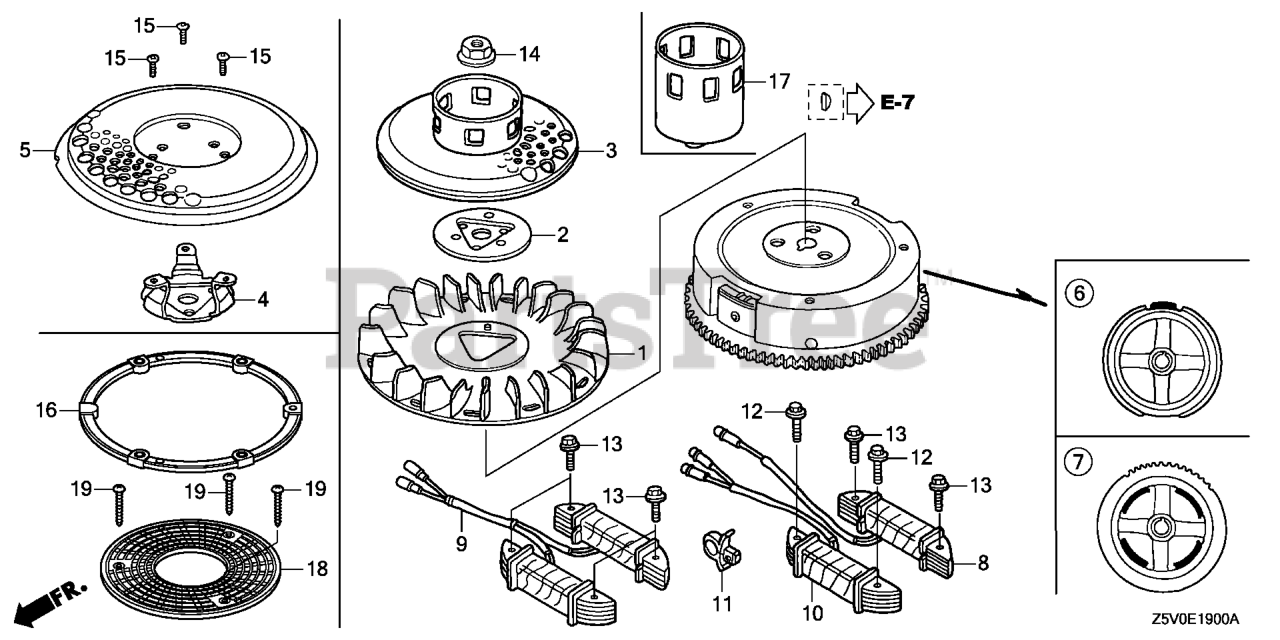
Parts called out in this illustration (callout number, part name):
1	FAN, COOLING
6	FLYWHEEL
14	NUT, SPECIAL (16MM) (1)
16	SPACER, RECOIL STARTER MOUNTING *R280* (POWER RED)
17	PULLEY, STARTER
18	GRID, SCREEN
19	SCREW, TAPPING (4X30) (PO)
